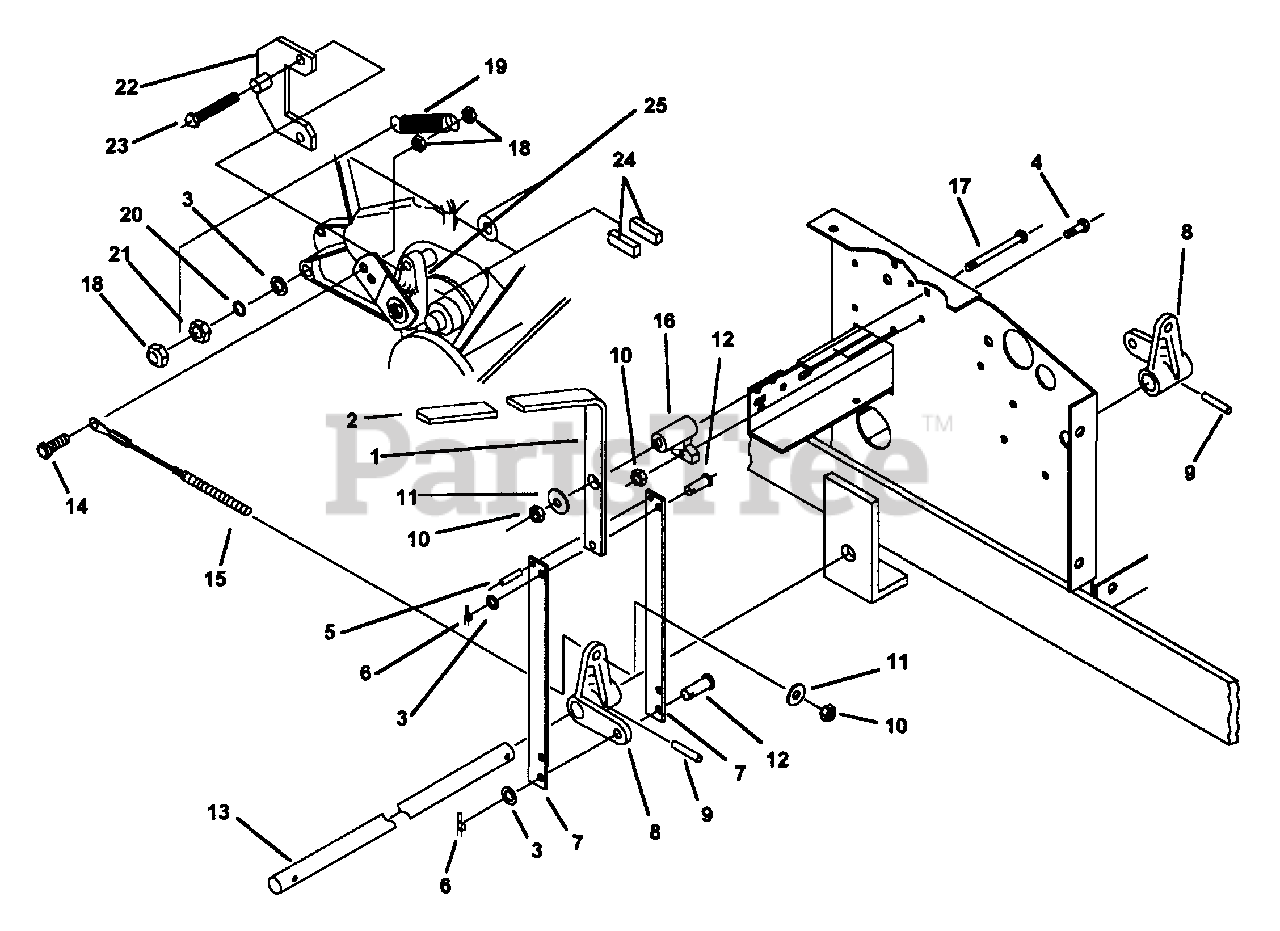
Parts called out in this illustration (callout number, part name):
1	BRAKE HANDLE
2	GRIP, HANDLE
3	WASHER, FLAT STD. 5/16"
4	BOLT, 1/4-20 X 1" GR.5
6	COTTER PIN, SELF LOCKING, 5/16 - 3/8
7	HANDLE LINK
8	BRAKE ARM
9	PIN, SPIRAL ROLL, 3/16 X 1" LIGHT DUTY
10	NUT, 1/4-20 NYLOCK
11	WASHER, FLAT STD. 1/4"
12	CLEVIS PIN, 5/16 X 7/8" LONG
14	BOLT, 5/16-18 X 3/4" GR.5
15	CABLE ASSEMBLY, BRAKE
16	BRAKE LEVER MOUNT
17	BOLT, 1/4-20 X 3", HEX HEAD
18	LOCKNUT, 5/16-18 STOVER
19	SPRING, EXT., 7/16" X 2-1/2"
20	LOCKWASHER, 5/16" SPLIT SPRING
21	NUT, 5/16-18 PLAIN
22	BRAKE STOP PLATE ASSEMBLY
23	BOLT, 1/4-20 X 1-1/2" GR. 5 W/PATCH (COMES W/GEARBOX)
24	BRAKE PUCK, REPLACEMENT
25	BRAKE YOKE, MACHINED, ASSEMBLED
